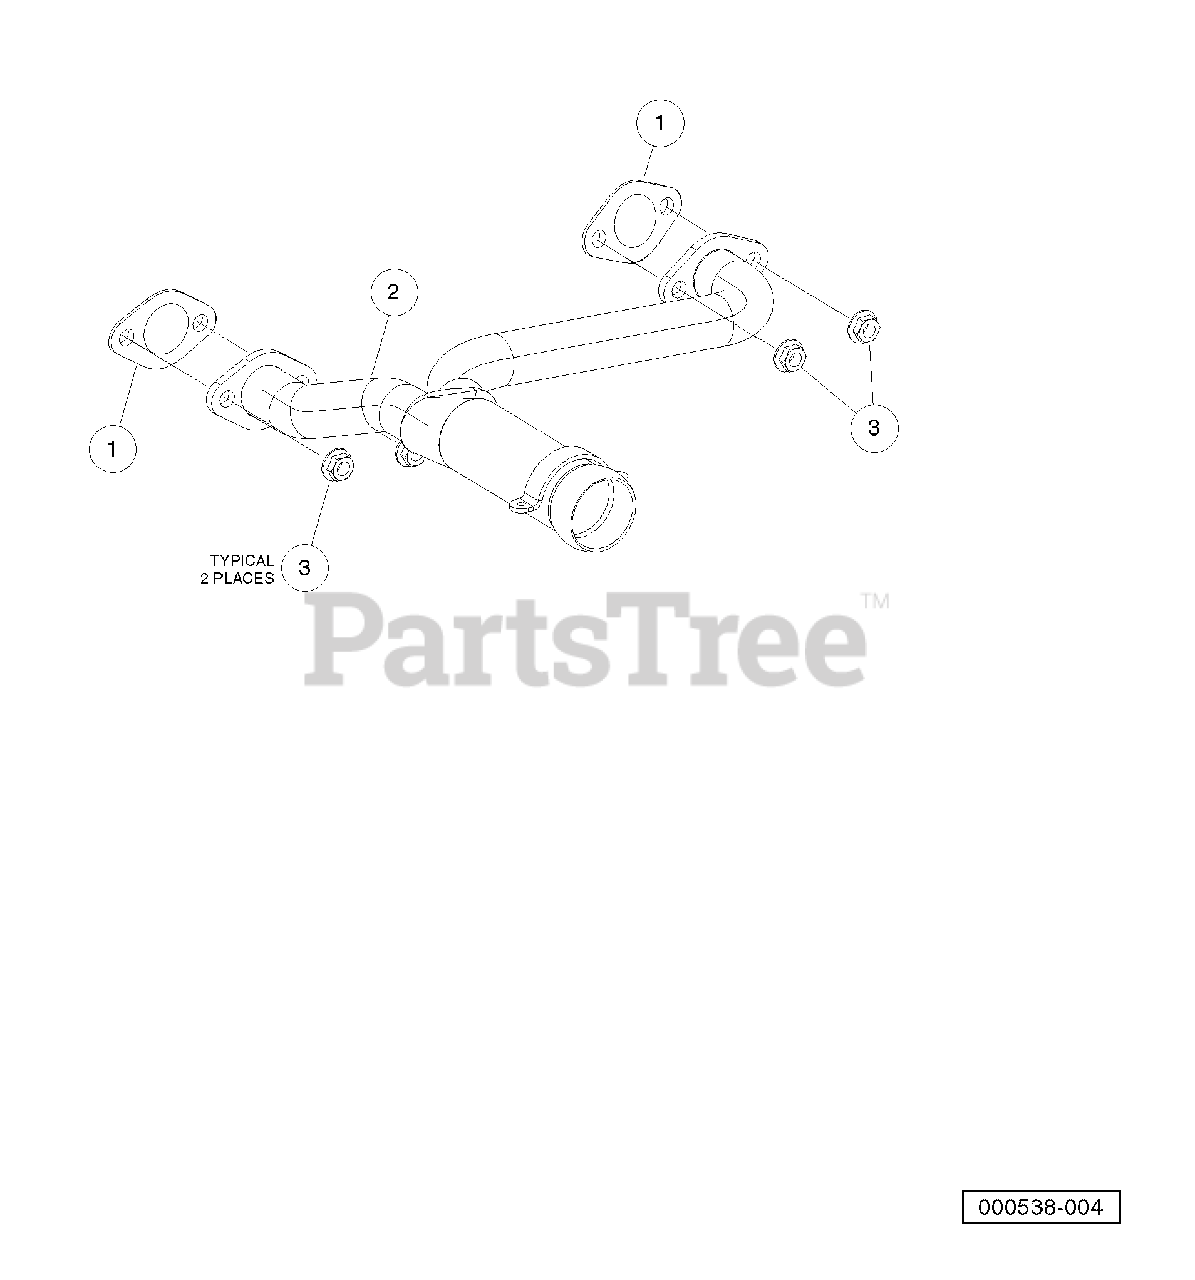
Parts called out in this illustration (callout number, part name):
1	Gasket, Exhaust Header, Fh680d
2	Header, Exhaust, Gas, Fh680d
3	Nut Flg, M8 X 1.25 Serrated
